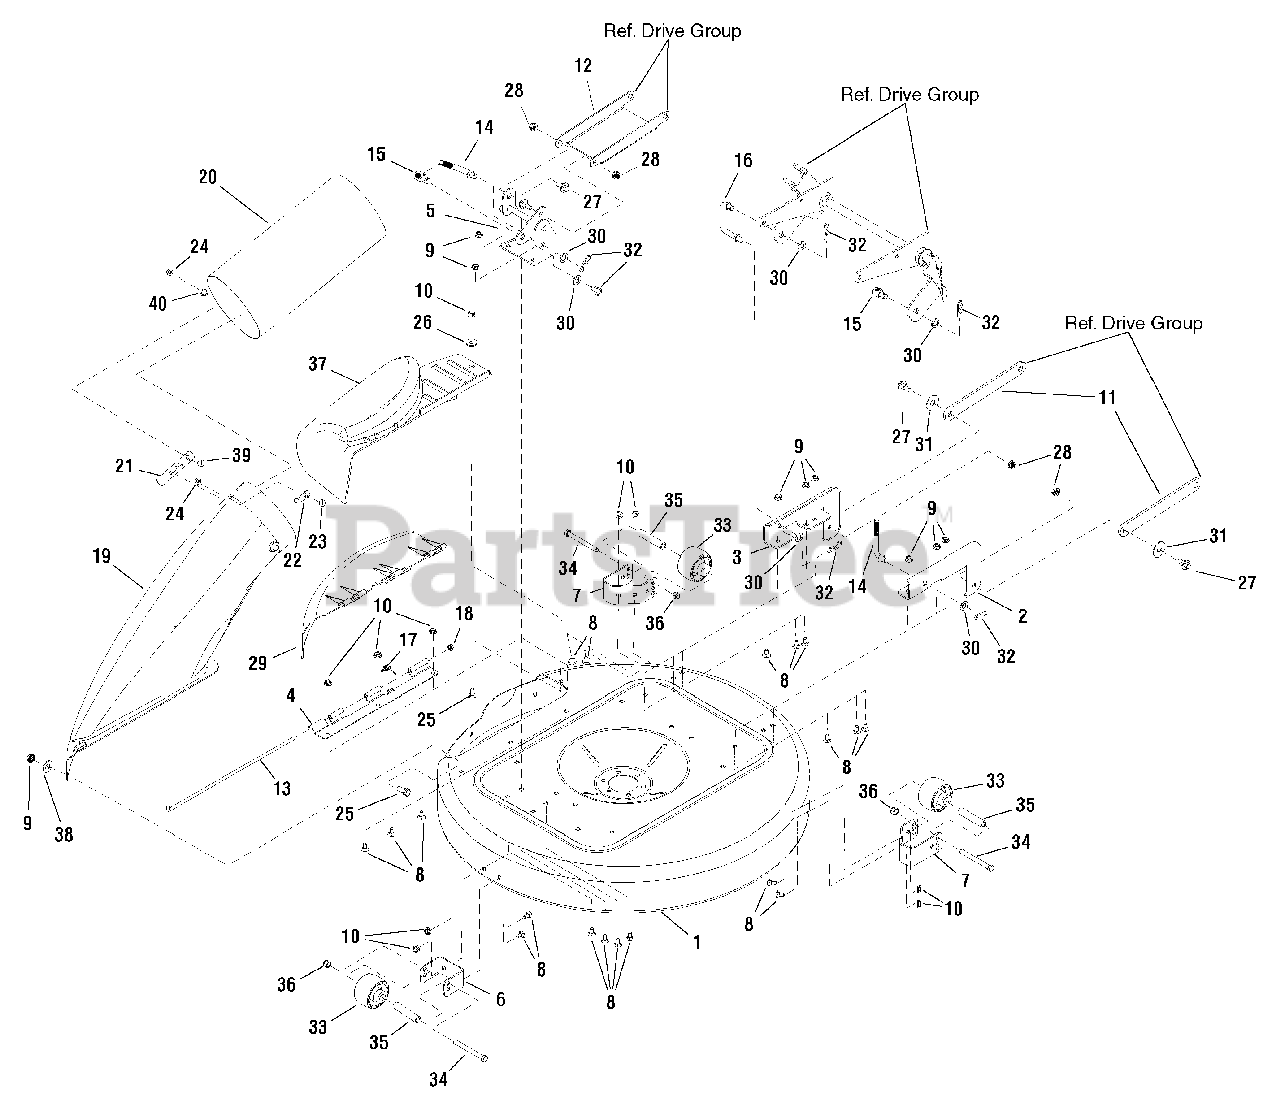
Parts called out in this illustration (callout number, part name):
1	BLADE HOUSING KIT, 33"
2	BRACKET, Top Deck LH
3	BRACKET, Top Deck RH
4	HINGE, Mulching Cover
5	FRONT DECK ADJUSTMENT ASSY
6	ANTI SCALP BRACKET, Front
7	ANTI SCALP BRACKET, Rear
8	BOLT, Carriage 5/16-18 x 5/8
9	NUT, Hex Flange, 5/16-18
10	NUT, Hex Flange Centerlock 5/16-18
11	ARM, Rear
12	HANGER, Front
13	ROD DEFLECTOR
14	ROD, Lift Link
15	ADJUSTING NUT
16	LIFT ROD, Fixed
17	SPRING, Deflector
18	PUSH CAP
19	REAR DISCHARGE CHUTE
20	CHUTE EXTENSION, Upper
21	RUBBER STRAP
22	PIN
23	BOLT, Carriage 1/4-20 x 5/8
24	NUT, Hex Flange Lock, 1/4-20
25	BOLT, Carriage, 5/16-18 x 3/4
26	WASHER, Flat, 5/16 x 1
27	BOLT, Shoulder, 3/8-16 x 1.10
28	NUT, Hex Flange, 3/8-16
29	MULCH COVER
30	WASHER, 1/2 x 7/8
31	WASHER, 1/2 x 1-1/2
32	HAIRPIN
33	WHEELS, Anti Scalp
34	CAPSCREW, Hex Head, 3/8-24 x 3/4, GR5
35	SPACER, 3" Long
36	NUT, Hex Nyloc, 3/8-24
37	DEFLECTOR, Chute
38	WASHER, Flat, 5/16
39	BOLT, 1/4-20 x 1
40	NUT, Keps Lock 1/4-20
